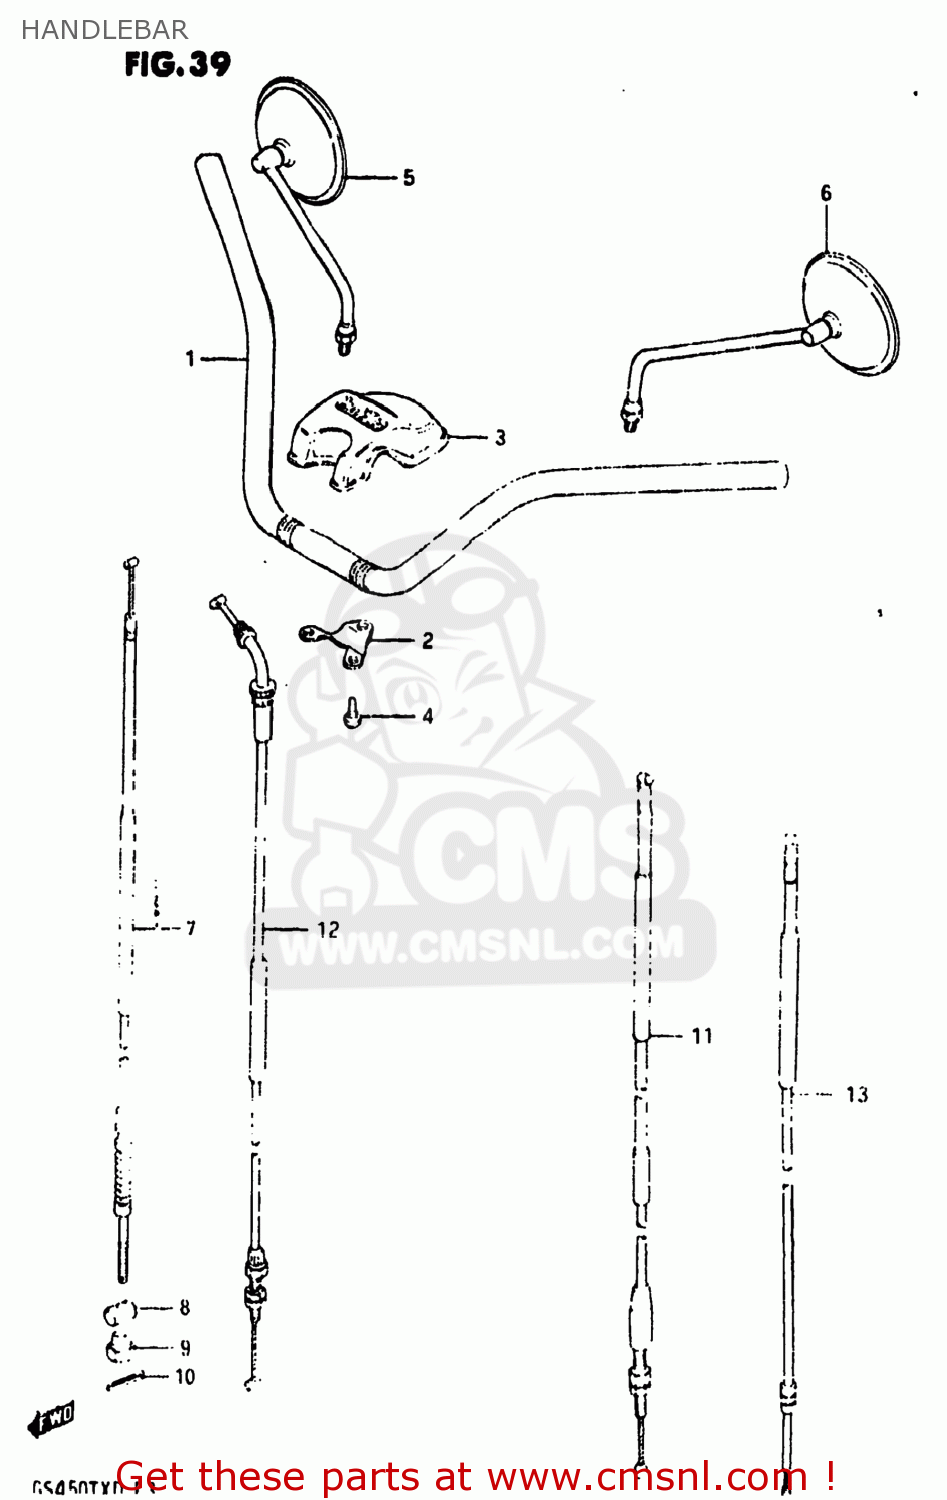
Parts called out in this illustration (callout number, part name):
1	HANDLEBAR
2	BRACKET,HEAD COVER
3	COVER,STEERING HEAD
4	SCREW
5	MIRROR ASSEMBLY,RIGHT
6	MIRROR ASSEMBLY,LEFT
7	CABLE ASSEMBLY,FRONT BRAKE
8	PIN
9	NUT (6MM)
10	PIN
11	CABLE ASSEMBLY,CLUTCH
12	CABLE ASSEMBLY,THROTTLE
13	CABLE ASSEMBLY,STARTER
